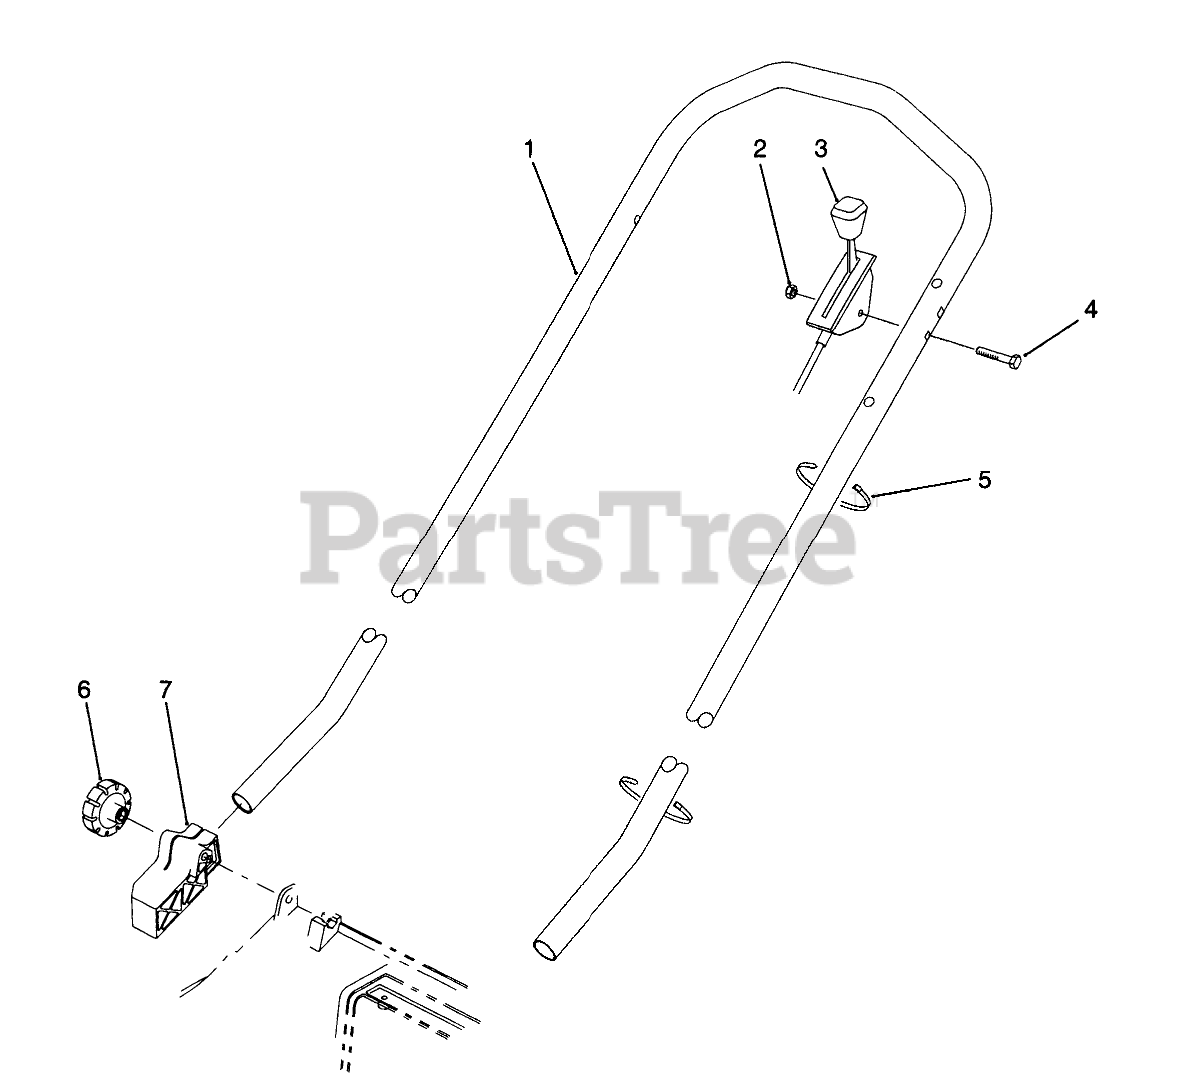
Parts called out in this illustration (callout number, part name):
1	Handle
2	NUT-LOCK, NI
3	Control-Throttle Bend Type #1 Sheath Lg. 57.50 Wire Lg. 2 1/2
4	SCREW-HANDLE
5	TIE-CABLE
7	MOUNT-HANDLE, RH
